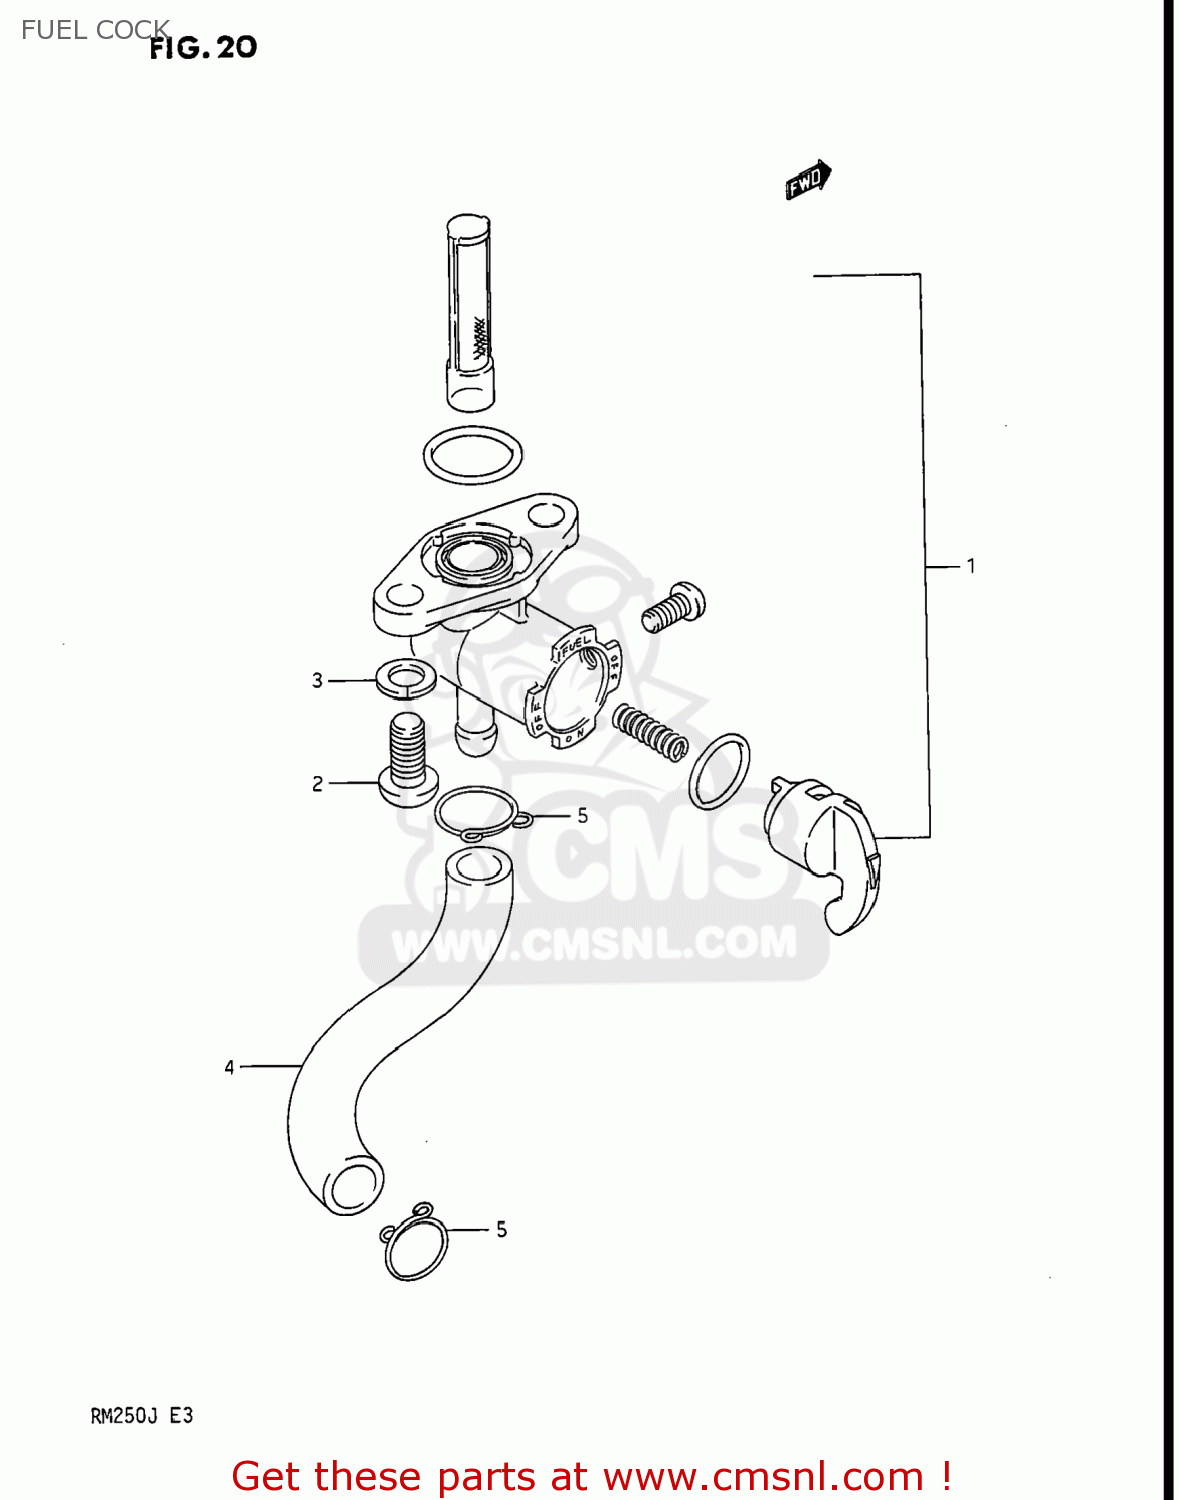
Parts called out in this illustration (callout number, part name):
1	COCK ASSEMBLY,FUEL
2	SCREW
3	WASHER,LOCK
4	HOSE
5	CLIP
